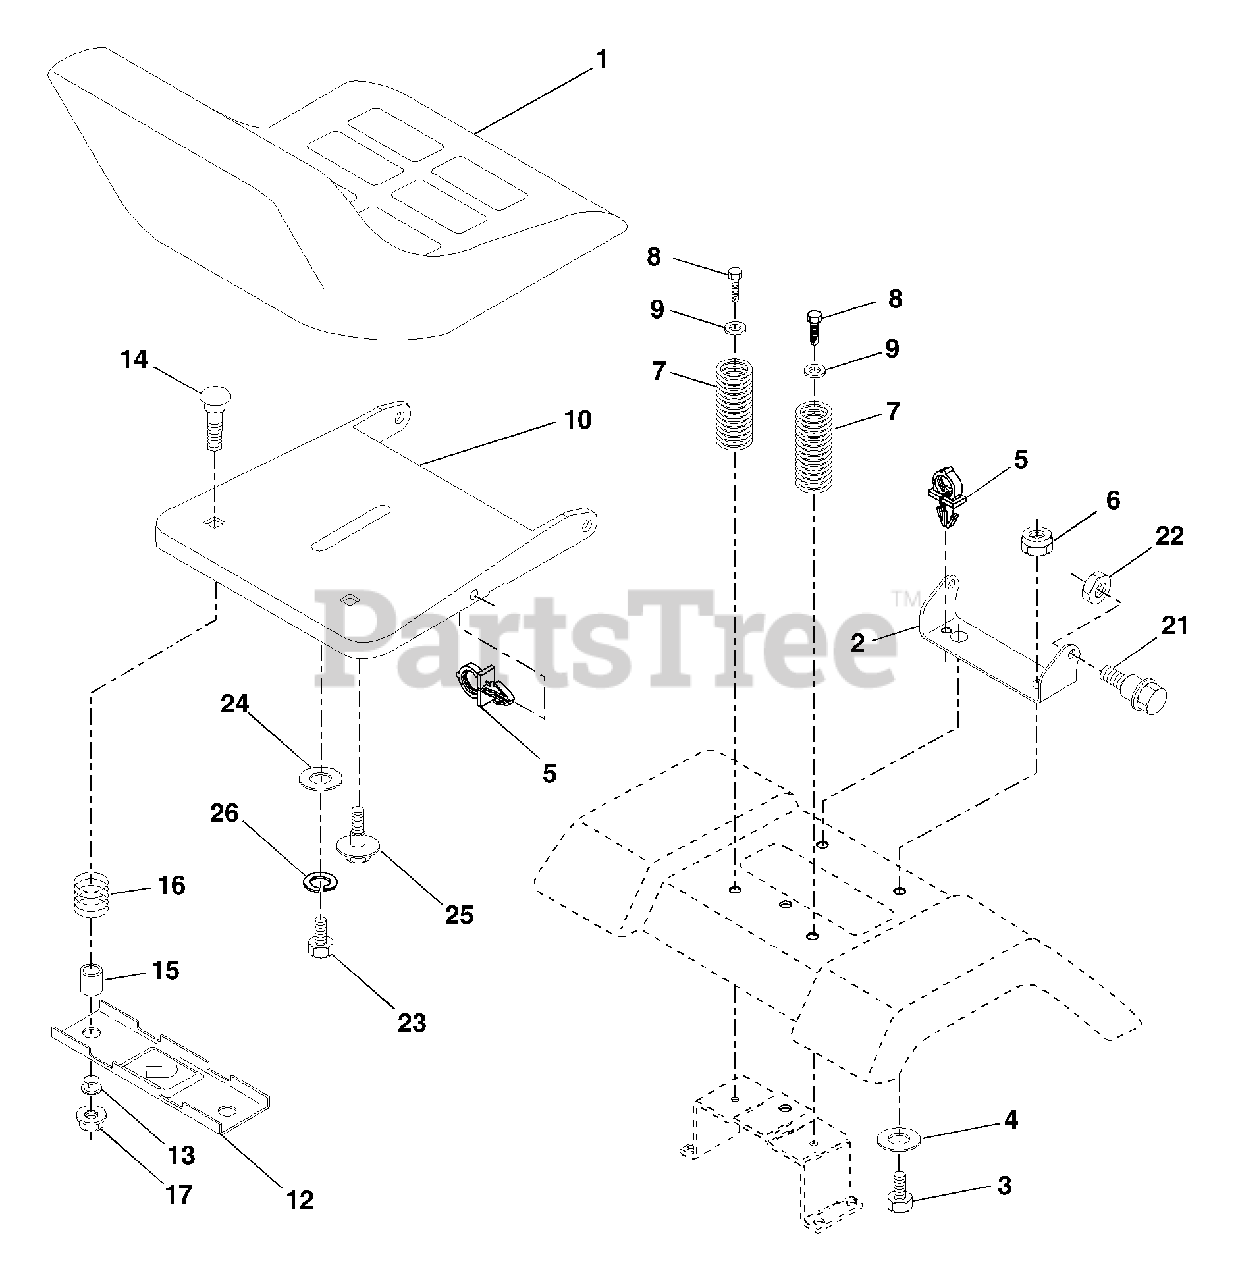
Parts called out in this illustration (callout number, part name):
2	Bracket Seat Pivot
3	Bolt Hex 3/8 - 16 x 1
4	Washer 13/32 x 1 x10Ga.
5	Clip Push-In Hinged
6	Nut Lock Hex w/Ins 3/8 - 16
7	Spring Seat Cprsn 2 250 Blk Zi
8	Screw 3/8-16 x 1.5
9	Washer 13/32 x 1 x 14 Ga
10	Pan Pnt Seat (Blk)
12	Bracket Pnt Mounting Switch
13	Bushing Snap Blk Nyl
14	Bolt Rdhd Sht Nk 1/4 - 20 x 1-1/2
15	Spacer Split .28 x .96
16	Spring Cprsn
17	Nut Lock 1/4 Lge Flg
21	Bolt Shoulder 5/16-18 Unc-2A
22	Nut Lock Hex w/Ins 5/16 - 18
23	Bolt Hex
24	Washer 17/32 x 1-3/16 x 12 Ga
25	Bolt Shoulder 5/16-18 x .62
26	Washer Lock Hvy Hlcl Spr 1/2
